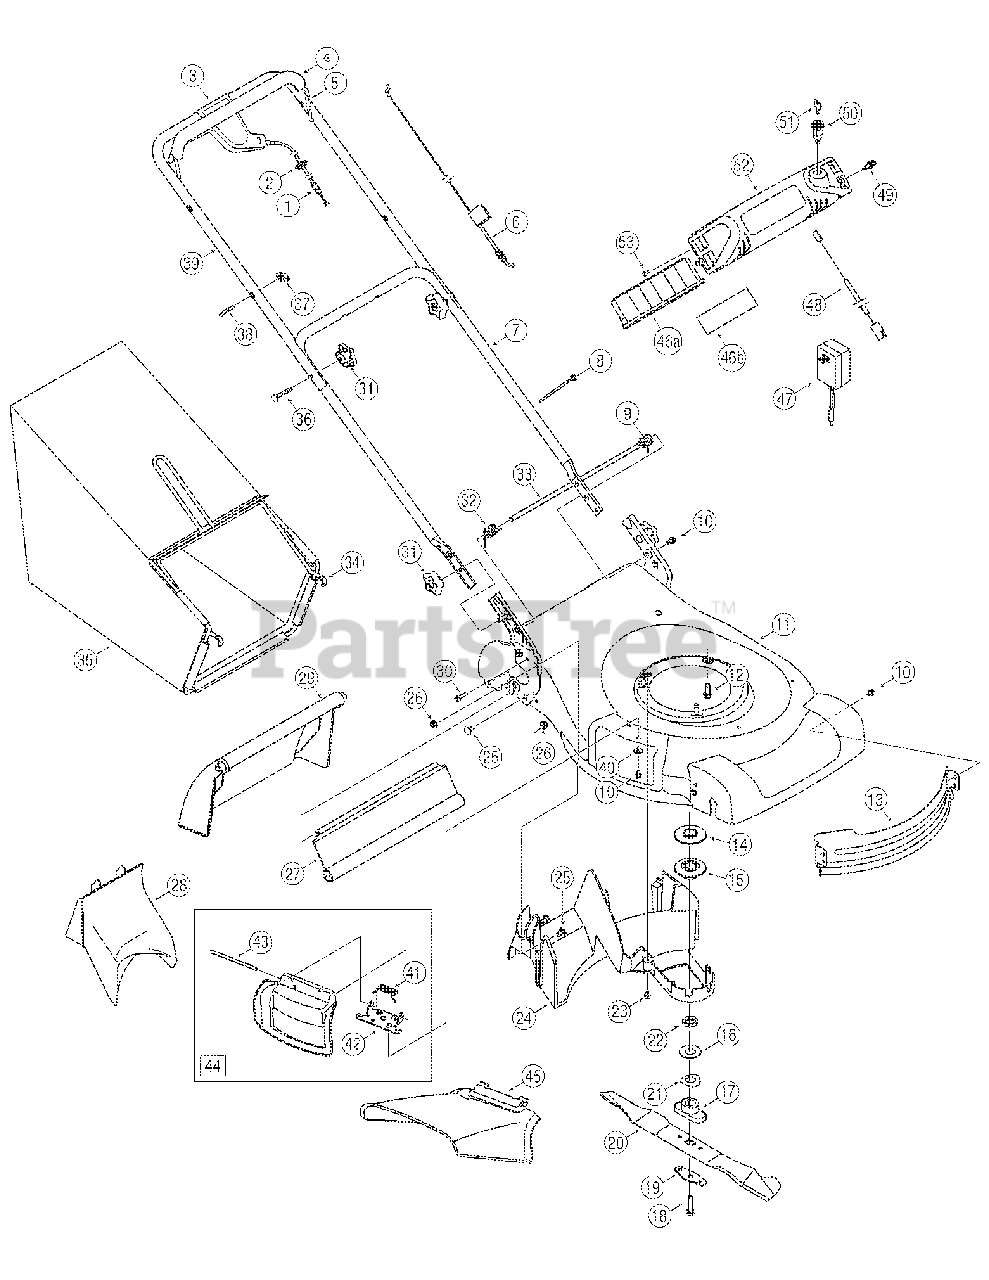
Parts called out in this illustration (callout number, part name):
1	Drive Cable
2	Rubber Grommet
3	Drive Control Assembly
4	Bail Cover
6	Control Cable
8	Cable Tie
9	Torsion Spring, LH
10	TT Screw, 1/4-20 x .500
12	TT Screw, 3/8-16 x 1.00
13	Deck Baffle
14	Upper Engine Pulley
15	Lower Engine Pulley
16	Flat Washer, .885 x 1.850 x.060
17	Blade Adapter
18	Screw, 3/8-24 x 1.50
19	Blade Bell Support
20	21" Mulching Blade
21	Spring Washer, .890 x 1.70 x .048
22	Sleeve Spacer
23	TT Screw, 1/4-20 x .375
24	Deck Baffle
25	Carriage Bolt, 5/16-18 x .62
26	Flange Lock Nut, 5/16-18
27	Trailshield
28	Mulch Plug
29	Rear Door
30	Screw, 1/4-15 x 1.00
31	Star Knob
32	Torsion Spring, RH
33	Door Pivot Rod
36	Carriage Bolt, 5/16-18 x 2.00
40	Bell Washer, .265 x .75 x .062
41	Torsion Spring
42	Chute Deflector Adapter
43	Hinge Pin
44	Mulch Plug Assembly
45	Side Discharge Chute
47	Battery Charger
48	Electric Starter Harness
50	Key Switch
51	Key
52	Battery Hsg. (used w/ref. #46a)
52	Battery Hsg. (used w/ref. #46b)
53	Screw, #10-16 x .750
